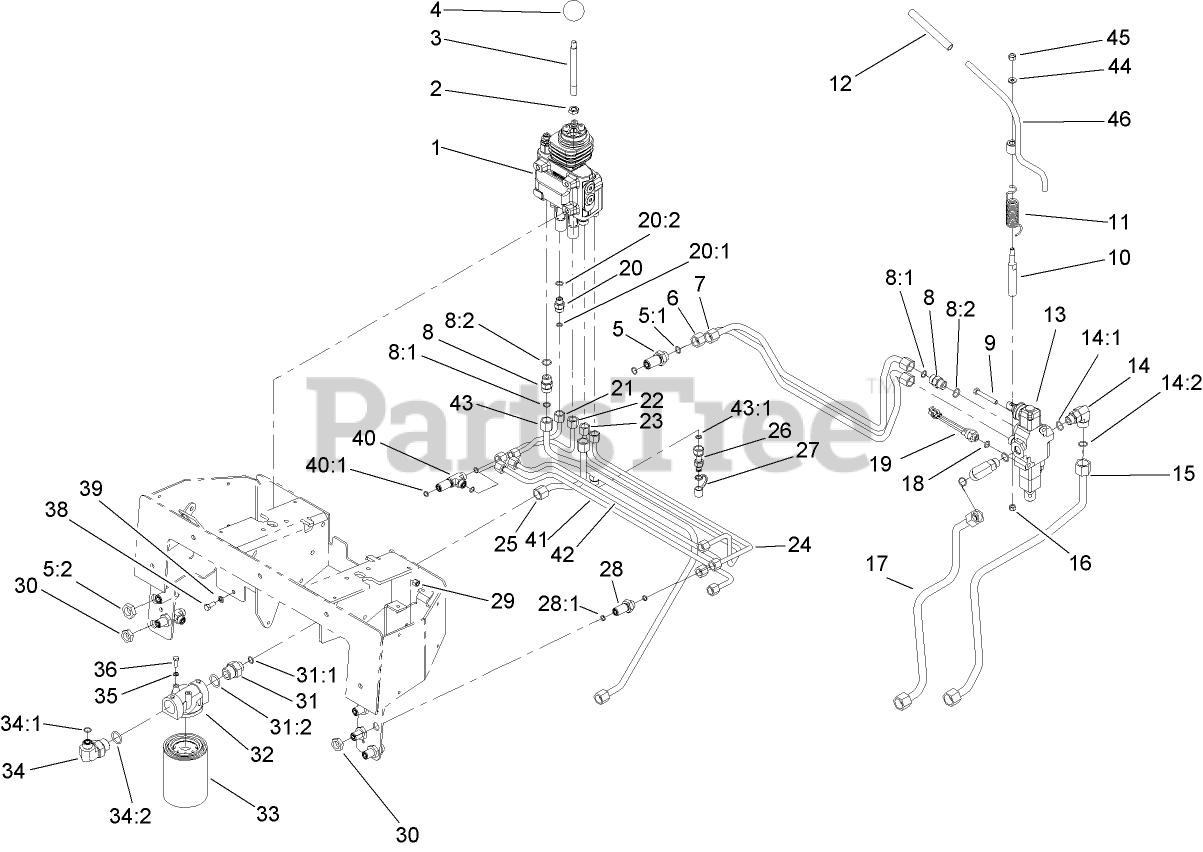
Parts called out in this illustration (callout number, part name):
1	2 SPOOL VALVE ASM
3	SHAFT-HANDLE, LOADER
5	FITTING-BULKHEAD
5:1	O-RING
5:2	NUT-BULKHEAD
6	TUBE-HYD
7	TUBE-HYD
8	FITTING-STRAIGHT
8:1	O-RING
8:2	O-RING
9	SCREW-HH
10	SPACER-HIFLO
11	SPRING-TORSION
12	GRIP-RUBBER
13	1 SPOOL VALVE ASM
14	Fitting-Elbow, 90 DEG
14:1	O-RING
14:2	O-RING
15	TUBE-HYD
16	SCREW
17	TUBE-HYD
18	O-RING
19	SWITCH-BALL
20	FITTING-STRAIGHT
20:1	O-RING
20:2	O-RING
21	TUBE-HYD
22	TUBE-HYD
23	TUBE-HYD
24	TUBE-HYD
25	TUBE-HYD
26	NIPPLE-TEST
27	CAP-DUST
28	FITTING-STRAIGHT, BULKHEAD
28:1	O-RING
29	NUT-LOCK, NI
30	NUT-LOCK
31	FITTING-STR
31:1	O-RING
31:2	O-RING
32	HEAD-FILTER
33	FILTER-OIL
34	FITTING-HYD, 90 DEG
34:1	O-RING
34:2	O-RING
35	WASHER-LOCK
36	SCREW-HH
38	SCREW-HH
39	WASHER-LOCK
40	FITTING-TEE, BULKHEAD
40:1	O-RING
41	TUBE-HYD
42	TUBE-HYD
43	HYD TUBE ASM
43:1	O-RING
44	WASHER-FLAT
45	NUT-LOCK, NI
46	LEVER-AUXILIARY
